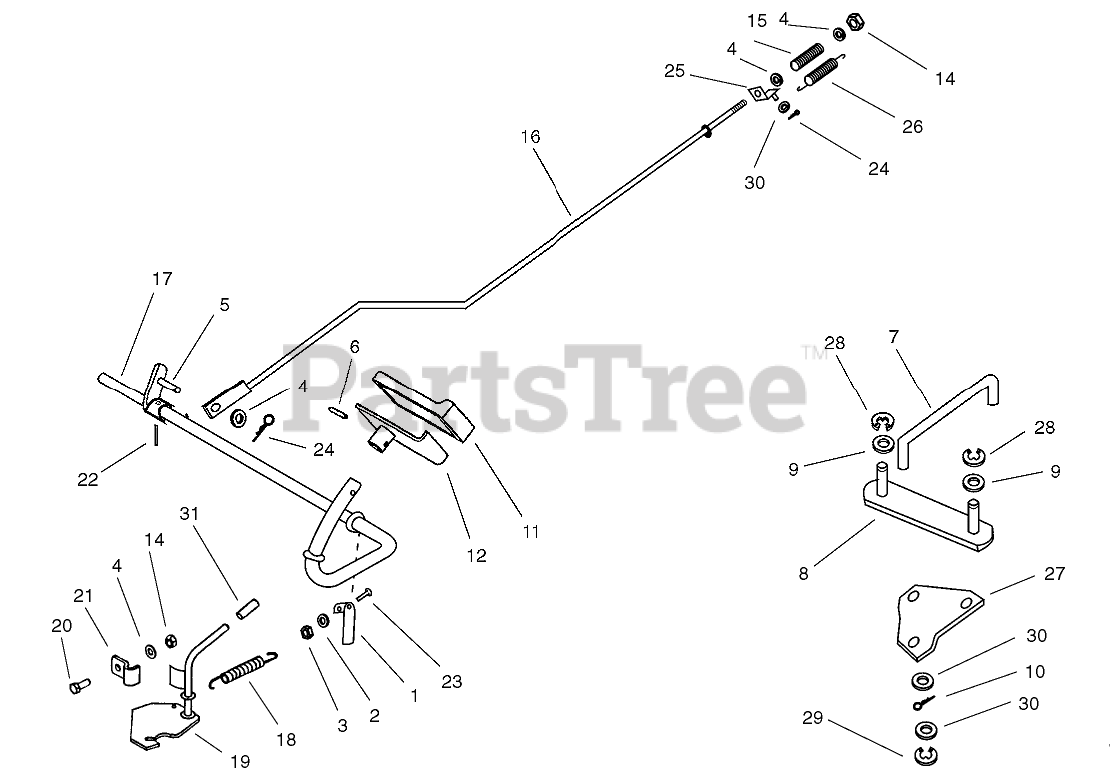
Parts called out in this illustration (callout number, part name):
1	LEVER-SPRING
2	WASHER
3	NUT-HEX
4	WASHER-PLAIN
5	BRACKET-ROD, BRAKE
6	PIN-SPRING
7	ROD-LEVER, BYPASS
8	Lever-Bypass
9	WASHER
10	PIN-COTTER
11	PAD-PEDAL
14	NUT-LOCK, NI
15	SPRING-BRAKE
16	ROD-CONNECTING, BRAKE
17	Shaft-Brake
18	SPRING-BRAKE, HAND
19	LEVER-BRAKE, HAND
20	SCREW-HH
21	CLAMP-LEVER, PARKING BRAKE
22	PIN-SPRING
23	SCREW-HEX
24	PIN-COTTER
25	BRACKET-ROD, BRAKE
26	SPRING
27	Plate-Bypass
28	STIRRUP
29	E-CLIP
30	WASHER-FLAT
